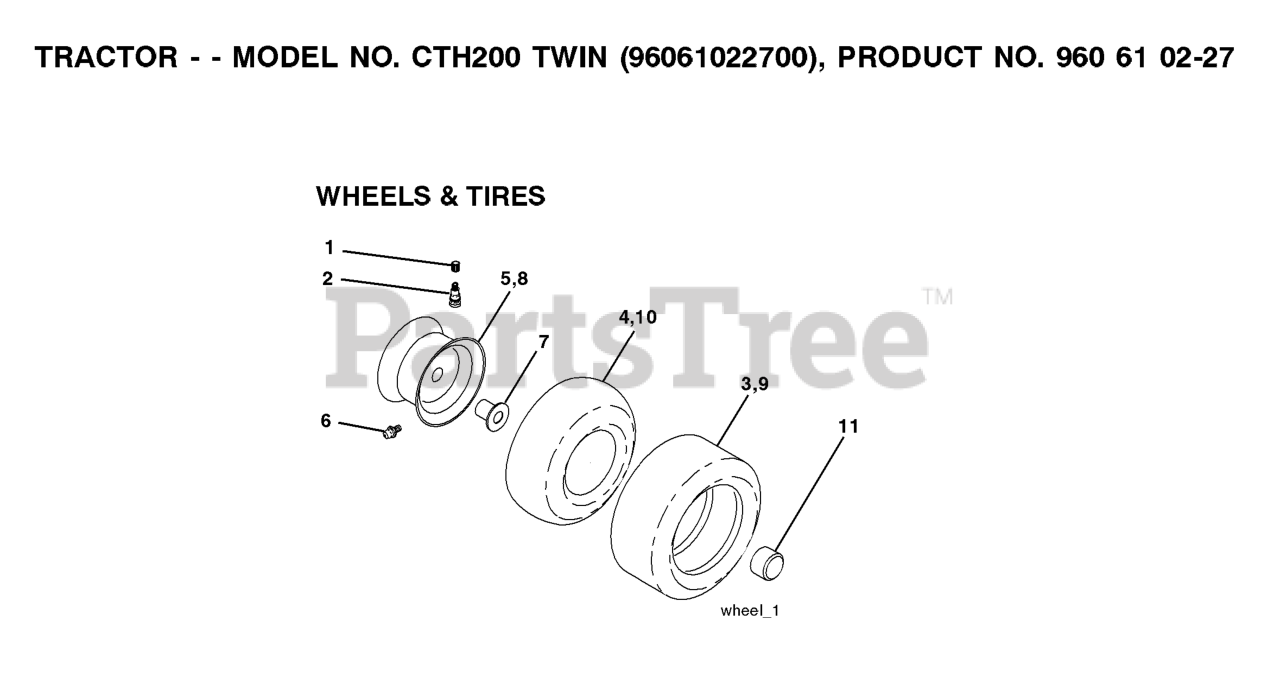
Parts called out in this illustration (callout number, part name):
2	VALVE STEM LT
3	TIRE HEAVY DUTY
4	TUBE.5.3/4.5/6
5	RIM ASM 6" FRONT SILVER
6	FITTING LT
7	BEARING T
8	RIM ASM 8" REAR SILVER
9	TIRE.TS.20X10-8
10	TUBE
11	CAP, AXLE BLK
